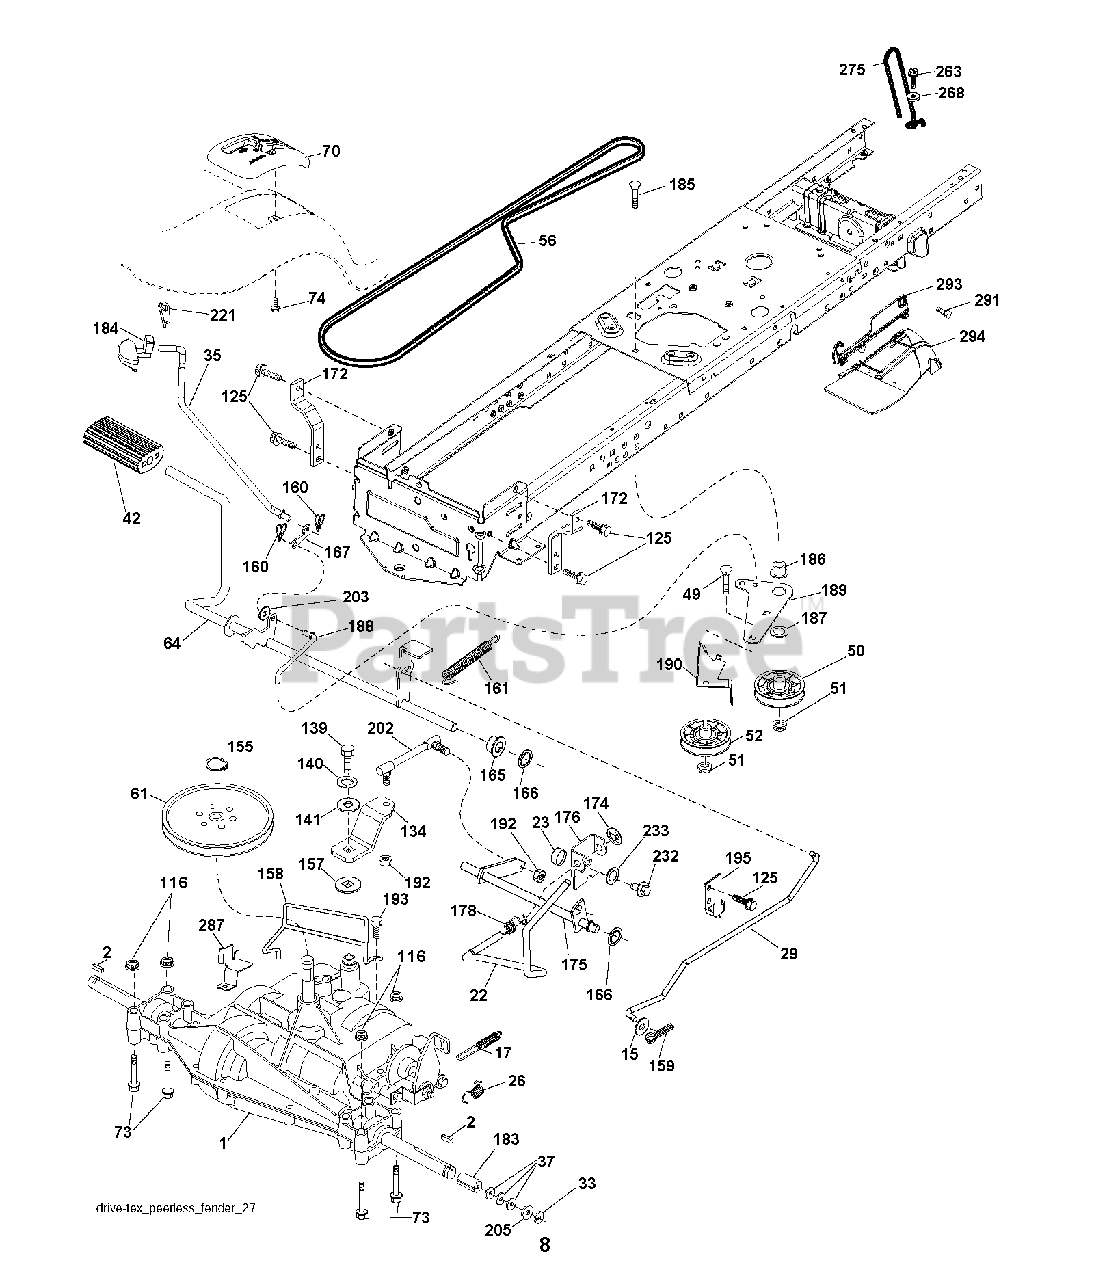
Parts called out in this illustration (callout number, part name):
2	SQUARE KEY
17	SPRING.BRAKE.PEERLESS.TEX
22	ROD.SHIFT.FENDER.TLT.2006
23	KNOB.DUCKHEAD.1/2
26	SPRING.BRAKE.RTN.GR.DR
29	ROD.BRAKE.PEERLESS
33	E-RING LT
35	ROD, BRAKE, PARK
42	PEDAL COVER T
49	BOLT
50	IDLER.FLAT.910.OFFSET
51	NUT LOCK FLG 3/8-16 UNC
52	IDLER.V-GROOVE.910.OFFSET
56	BELT, V GROUND DRIVE 95 25
64	SHAFT.ASM.PEDAL.BRAKE.
70	CONSOLE.SHIFT.
73	BOLT HEX 5/16-18 GR 5
74	SCREW.HI-LO.CONSOLE
116	NUT LOCK HEX FLANGE 5/16-18
125	SCREW
134	ARM SHIFT
139	BOLT 1/4-28X3/4
140	LOCKWASHER
141	WASHER LT
155	RETAINING RING LT
157	WASH-SHFT PLT LT
158	KEEPER.PMS.18/20.D4365
159	COTTER PIN
160	RETAINER CLIP
161	SPRING, RETURN LT
165	BUSHING.SHAFT.BRAKE.HAND
166	NUT.PUSH.625.2006
167	LATCH.BRAKE.SPRING
172	STRAP.TRQ.LH.GEAR.DRIV
174	NUT.PUSH.500.2006
175	SHAFT ASM SHIFT
176	ARM.CLEVIS.ROD.SHIFT
178	SPRING.SHIFT.GT2006
183	SPACER AXLE
184	HANDLE PARKING BRAKE
186	SPACER.RETAINER
187	WASHER 12/32X2X10GA
188	LINK.CLUTCH.GROUND.DRIVE
189	BELLCRANK.GROUND.DRIVE.TEX.
190	KEEPER.BELLCRANK.DRIVE
192	NUT LOCK CENTER 1/4 -28 FNTHD
193	SCREW 5/16"
195	BRKT.ROD.BRAKE.PEERLES
202	LINK.SHIFT.PMST.18"
203	WASHER
221	RETAINER.SPRING.CLIP.H
232	BOLT FIN HEX 7/16-14 X 1
233	WASHER SERRATED
263	SCREW, 3/8-16X3/4
268	WASHER
291	SHOULDER BOLT 5/16-18TT
